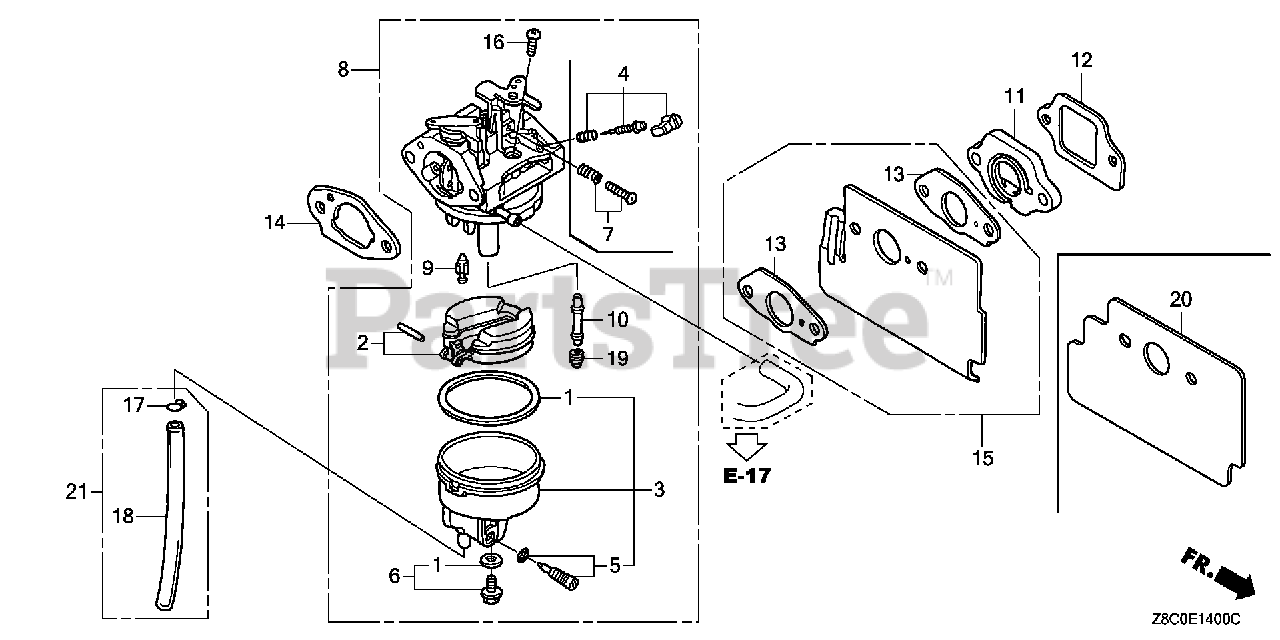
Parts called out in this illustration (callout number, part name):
1	GASKET SET
3	CHAMBER SET, FLOAT
4	SCREW SET (CARBURETOR NO.)
5	SCREW SET, DRAIN
6	SCREW SET
7	SCREW SET (THROTTLE STOP) (CARBURETOR NO.)
8	CARBURETOR ASSY. (BB61K A)
8	CARBURETOR ASSY. (BB61K B)
9	VALVE, FLOAT
10	NOZZLE, MAIN (CARBURETOR NO.)
11	INSULATOR, CARBURETOR
12	GASKET, INSULATOR
13	GASKET, CARBURETOR
14	GASKET, CARBURETOR
15	GUIDE, AIR
16	SCREW, PAN (5X6)
17	CLIP, TUBE (B6.5)
18	BULK HOSE, VINYL (4X7X8000) (4X7X150)
19	JET, MAIN (#62)
19	JET, MAIN (#65)
19	JET, MAIN (#68)
20	GUIDE, AIR
